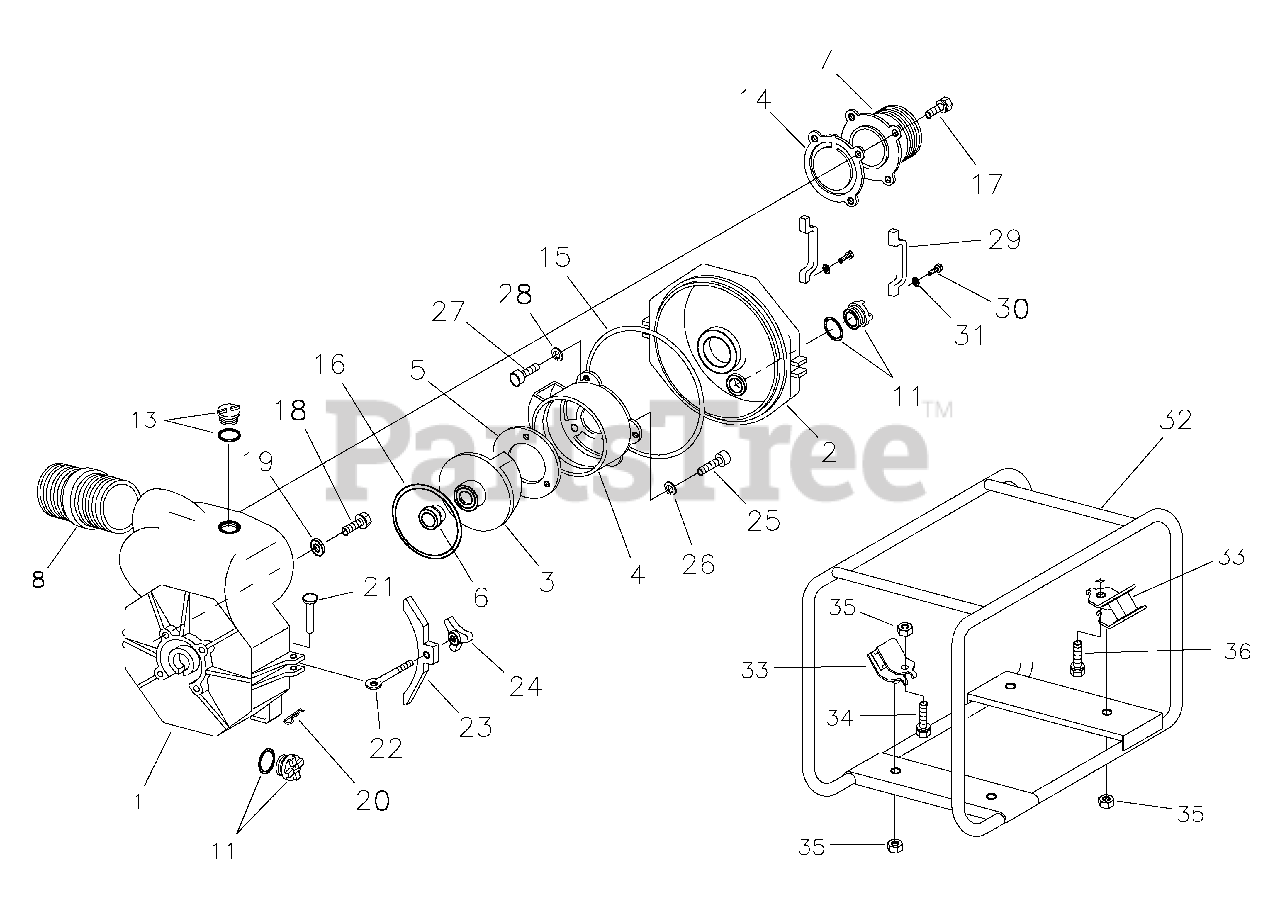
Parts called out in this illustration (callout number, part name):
6	Seal, Mechanical
7	Valve Case, BSP, 2"
8	Fitting, Pipe, BSP, 2"
13	Assy, Priming Plug
17	Hex Bolt, M8 x 25
18	Flange Bolt, M8 x 50
23	Casing Cover Holder
25	Hex Socket Bolt, M6 x 16
26	Lock Washer, M6
27	Hex Socket Bolt, M8 x 20
28	Lock Washer, M8
29	Drain Cover Handle
30	Hex Bolt, M6 x 25
31	Washer, M6
33	Anti Vibration, Rubber
34	Hex Bolt, M8 x 40
35	Flange Nut, M8
36	Hex Bolt, M8 x 20
